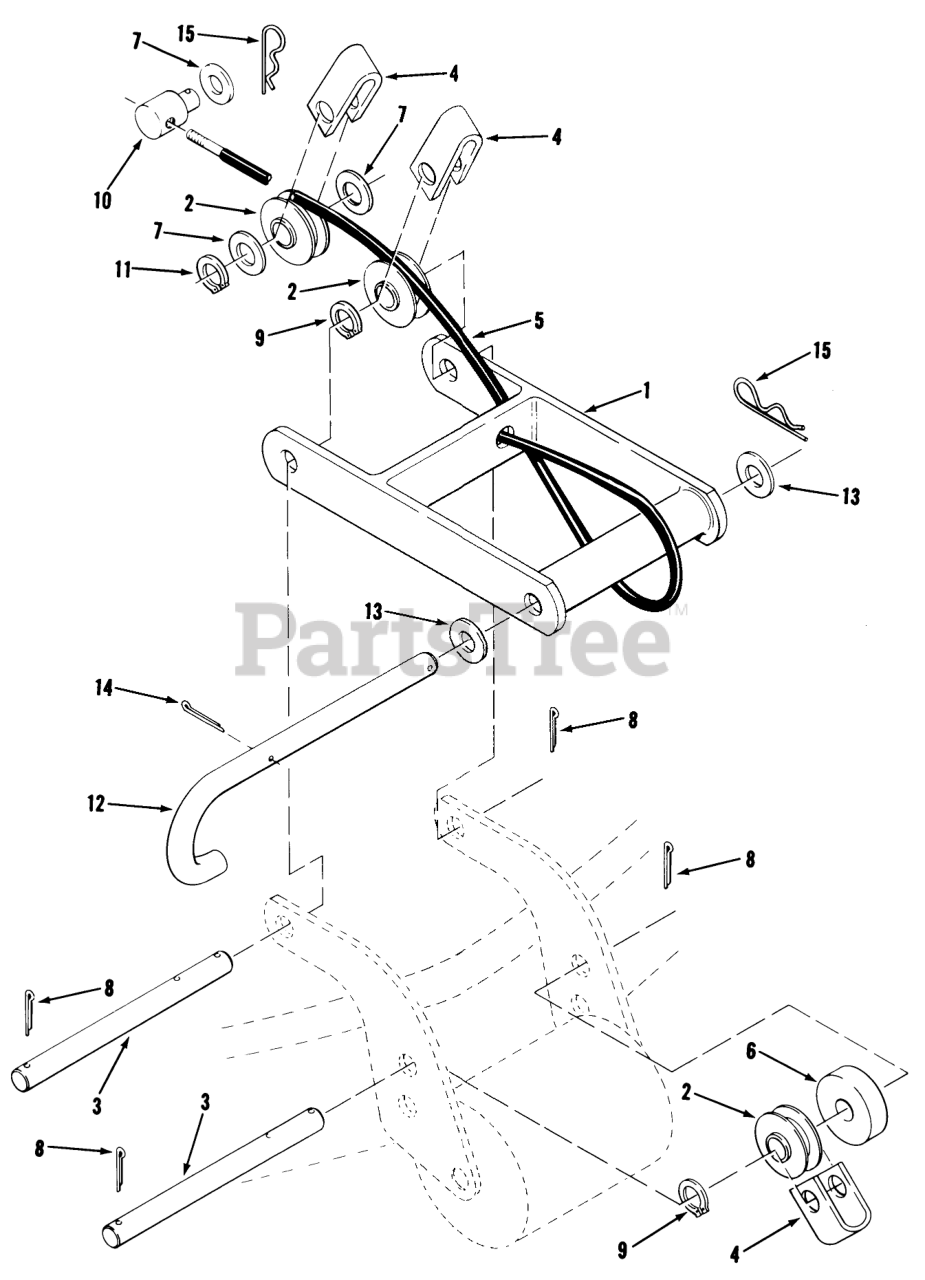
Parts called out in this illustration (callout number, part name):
1	Front Mount
2	ROLLER-CABLE
3	Rod
4	STRAP-CABLE
5	ASSY-CABLE
5	ASSY-CABLE 36IN&42IN
6	SPACER
7	Washer
8	Pop Rivet
9	GRIP RING
10	TRUNNION-CLUTCH ROD
12	"J" Pin
13	Washer
15	Hairpin Cotter
